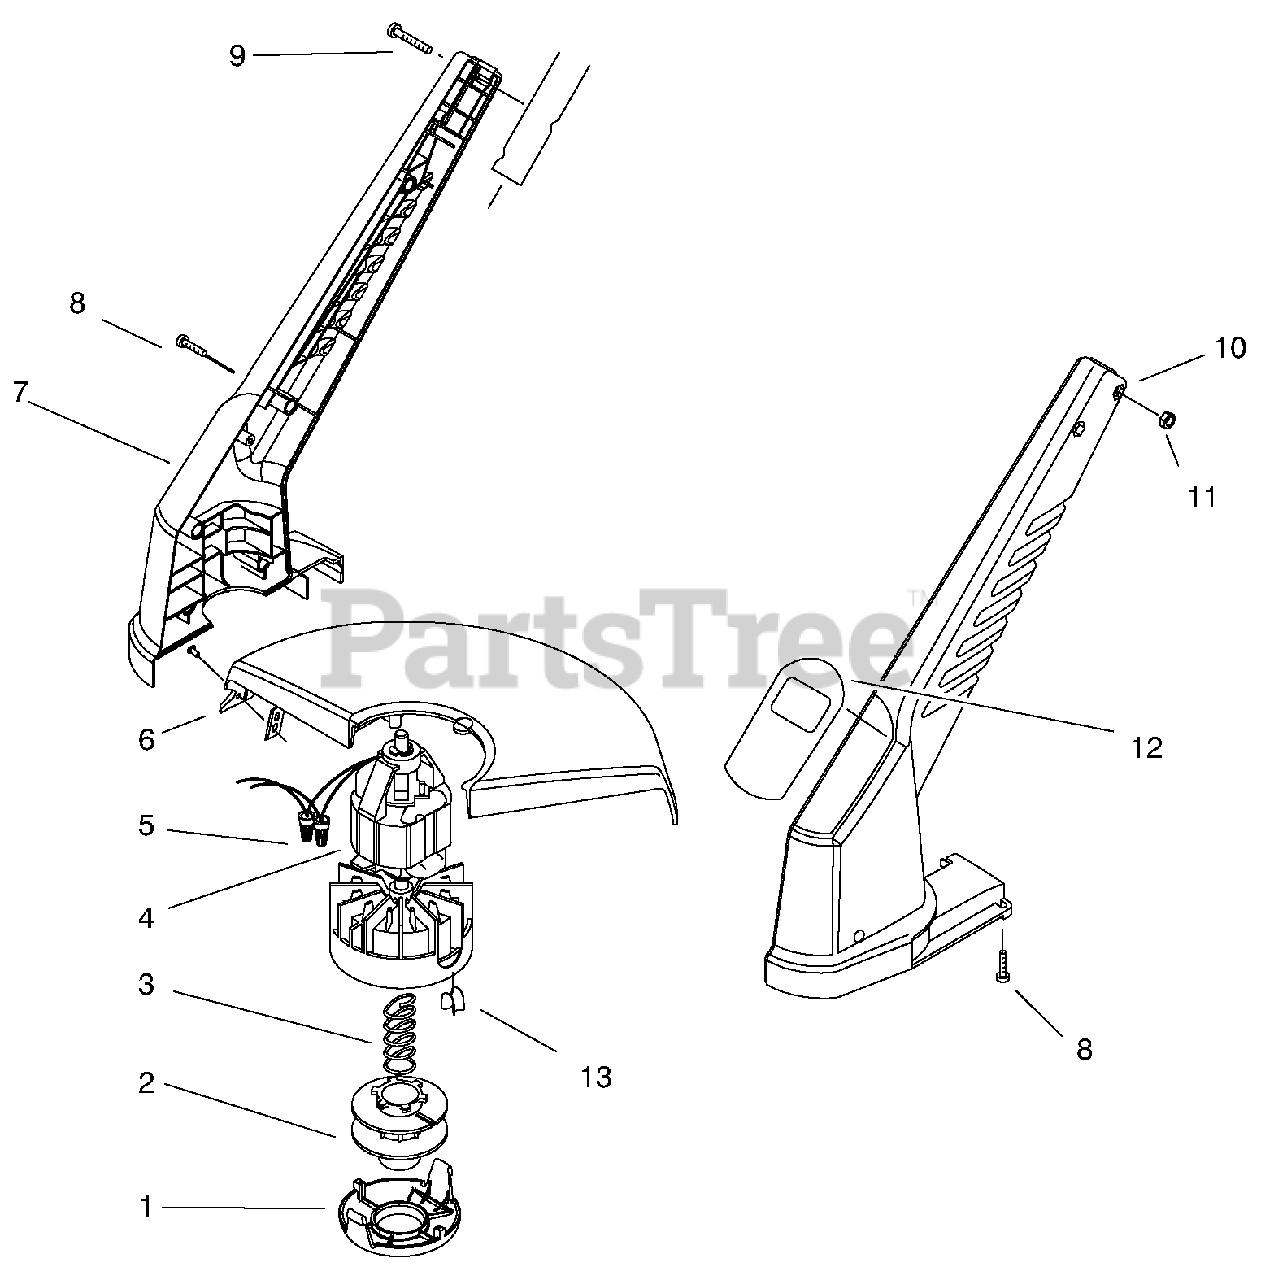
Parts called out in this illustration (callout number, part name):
4	Motor Assembly (Incl. Ref. #13)
5	Connector-Wire Nut
6	Shield-10"
7	Housing R.H.
9	Screw-Pan Hd.
10	Housing L.H.
12	Decal-10" Trimmer
